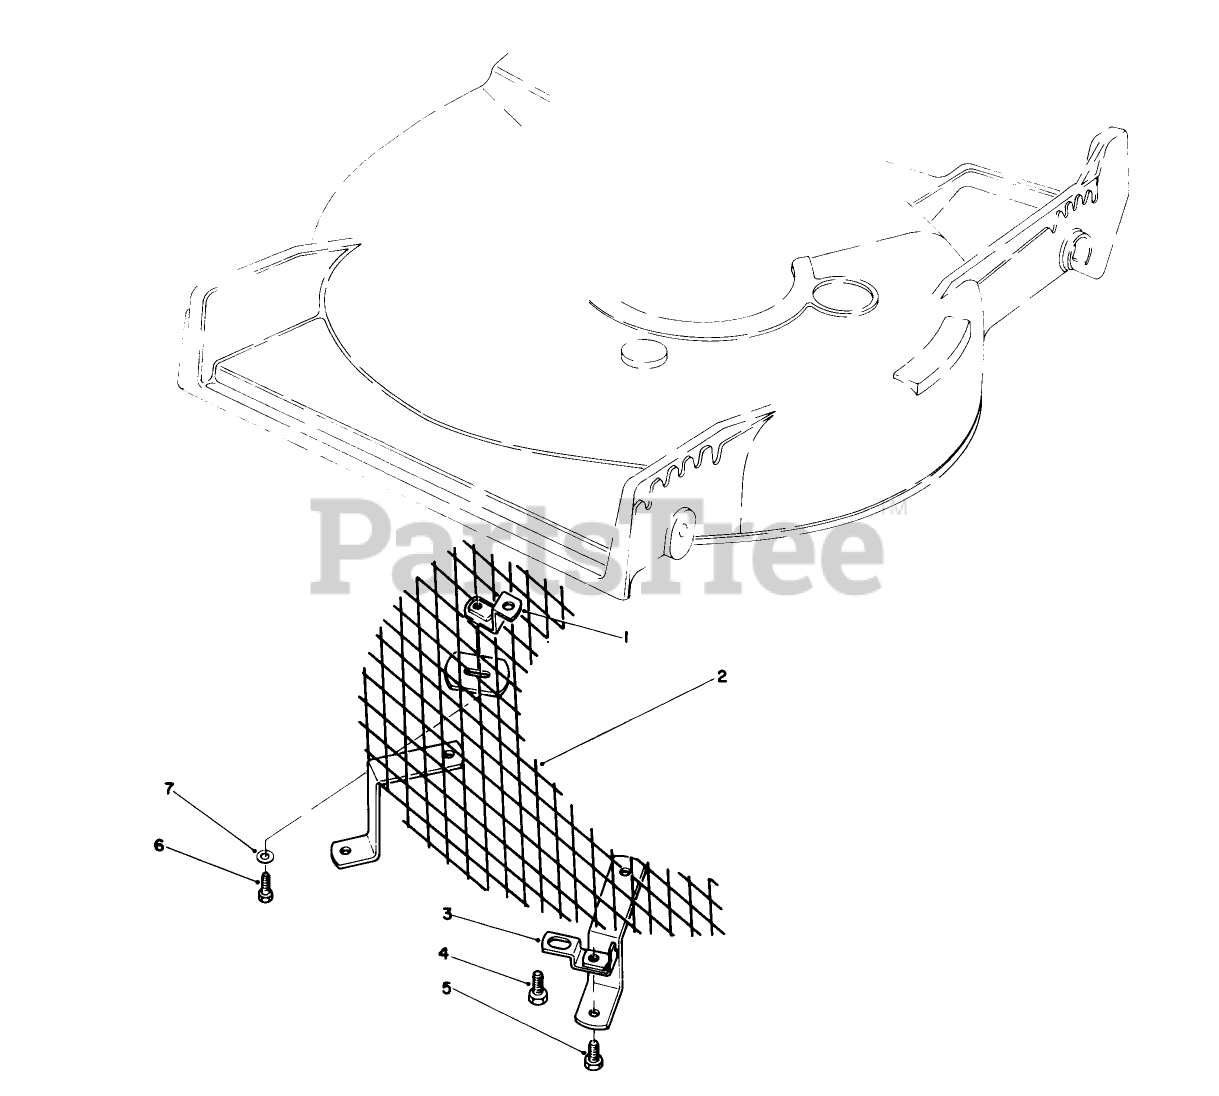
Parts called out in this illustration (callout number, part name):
1	BRACKET WA
3	MTG. BRACKET W.A.
4	SCREW-THD ROLL, HWH
5	SCREW-HH
6	SCREW-HH
7	WASHER-FLAT
